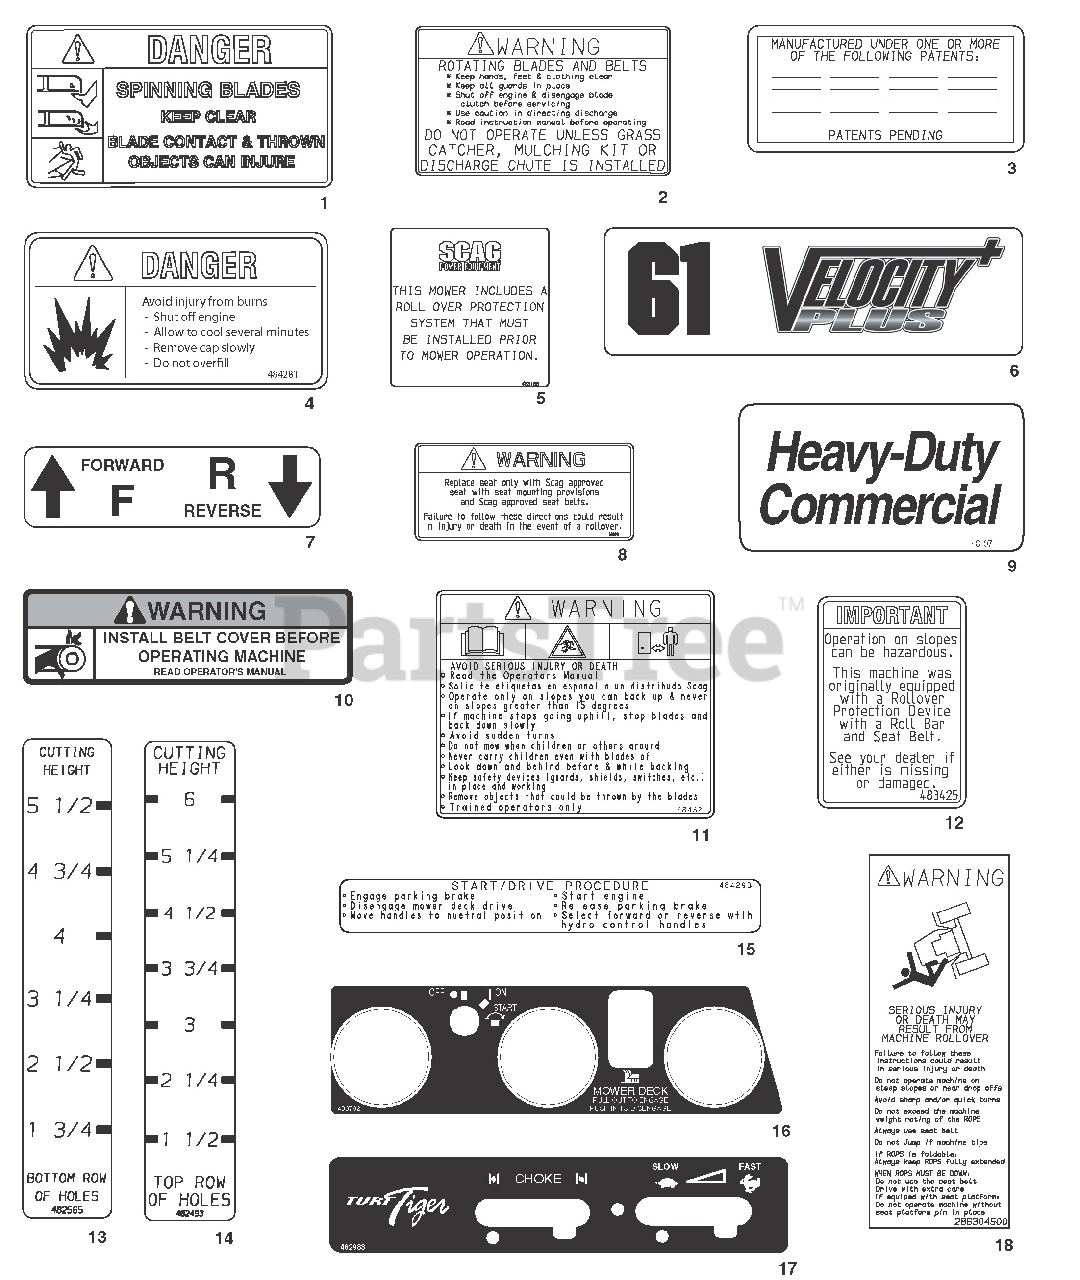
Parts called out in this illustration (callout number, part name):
1	Decal, Danger-Spinning Blades
2	Decal, Warning-Rotating Blades
3	Decal, Patents
4	Decal, Fuel Tank
5	Decal, ROPS
6	Decal, 61" Velocity Plus
7	Decal, Traction Control
8	Decal, Seat Replacement
9	Decal, Heavy Duty Commercial
10	Decal, Belt Cover
11	Decal, Warning
12	Decal, ROPS
13	Decal, Cutting Height - Lower
14	Decal, Cutting Height - Upper
15	Decal, Start/Drive Procedure
16	Decal, Instrument Panel - Upper
17	Decal, Instrument Panel - Lower
18	Decal, ROPS Warning
